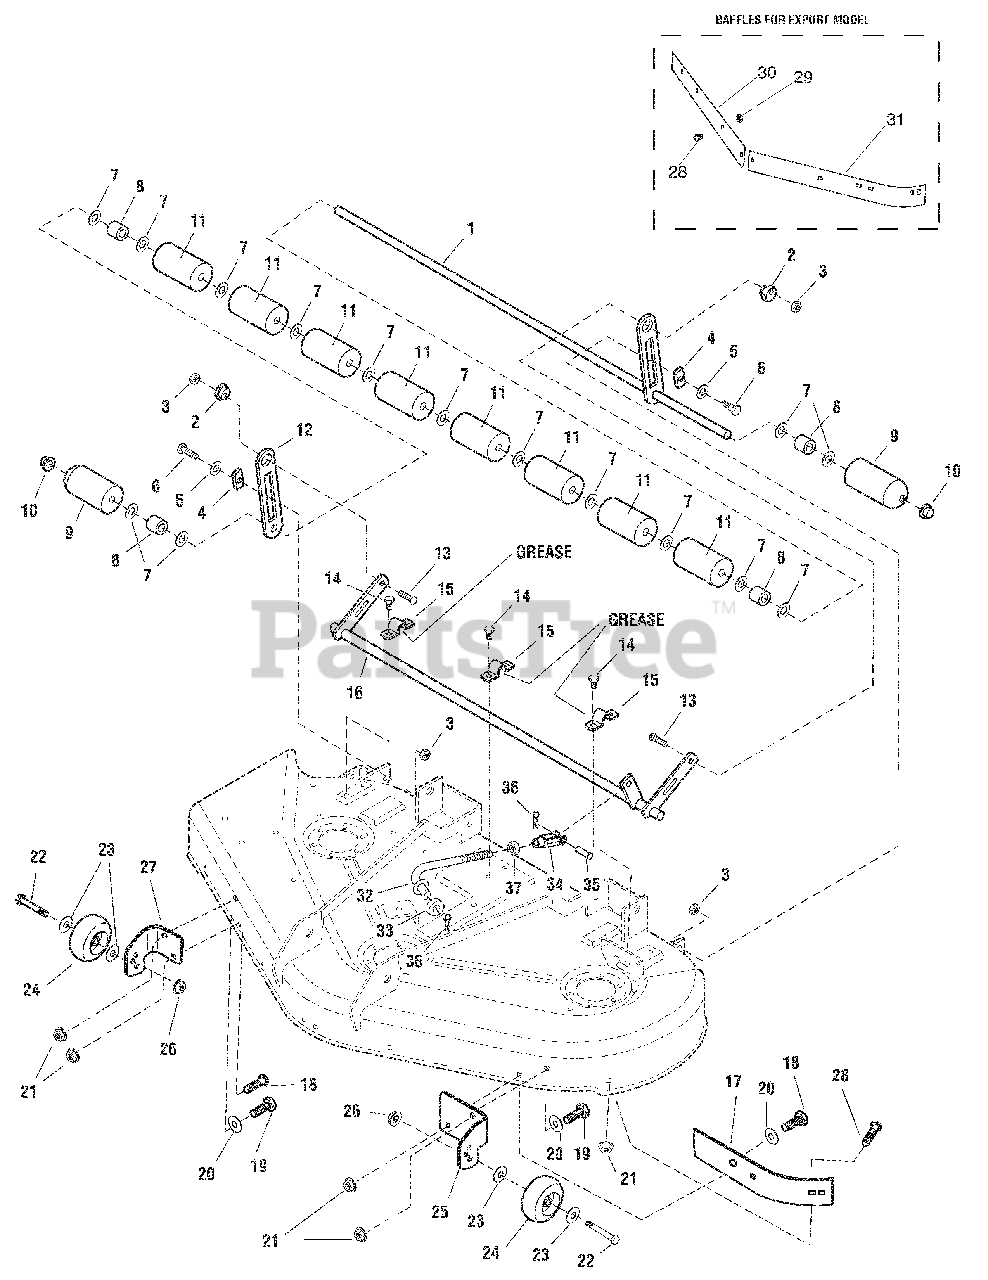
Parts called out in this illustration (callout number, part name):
1	WELD, SHAFT, ROLLER,50
2	NUT, HEX ADJUSTING .990DIA .687TH PM YEL
3	NUT, HEX TOP LOCK SPIRAL K FLNG, 3/8-16 YEL
4	SLIDE, .803 X 1.7
5	WASHER, 0500 (0.53IDX1.25X.08THK) BLK
6	BOLT, SHLDR, 3/8-16 1.34LG .50SH G5 BLK
7	WASHER, 0.625 (0.66IDX1.12X.11THK) BLK
8	SPACER, .876 OD X .666 ID X 1.25 LG
9	ROLLER, ROUNDED
10	NUT, PUSH FOR .625 DIA STUD CAPPED BLK
11	ROLLER
12	BAR, ROLLER
13	BOLT, RD HD SH SQ NK 3/8-16X1.500 G5 BLK
14	CAPSCREW, Hex Washer Head Taptite, 5/16-18X0.750BLK
15	STRAP, Rocker Shaft
16	WELD, SHAFT, DECK LIFT, 50"
17	SHORT BLOWOUT BAFFLE BLACK
18	BOLT, 5/16-18 X 1", CARRIAGE
19	CAPSCREW, HEX HEAD, 5/16-18 X 1
20	WASHER, 5/16" SAE
21	NUT, 5/16-18 HEX NYLOCK FLANGE
22	BOLT, WHEEL 3/8-16X2.781 .750 THRD YELLOW
23	WASHER, 0500 (0.51IDX0.87ODX.06THK) BLK
24	GAUGE WHEEL
25	BRACKET, GAUGE WHEEL, LH
26	NUT, 3/8-16 HEX NYLON FLANGE
27	BRACKET, GAUGE WHEEL, RH
28	BOLT, 5/16-18 X 3/4", CARRIAGE
29	NUT, 5/16 - 18 HEX NYLON LOCK
30	BLOWOUT BAFFLE, RH 50" MOWER - BLACK
31	BLOWOUT BAFFLE, LH 50" MOWER - BLACK
32	ROD, DECK LIFT LINKAGE
33	SPACER, HYDRO PULLEY
34	CLEVIS, 1/2-20, STEEL
35	PIN, CLEVIS, 1/2 X 1 1/2, YZP
36	PIN, HAIR, .0915 X 1-7/8
37	NUT, 1/2-20 HEX JAM
